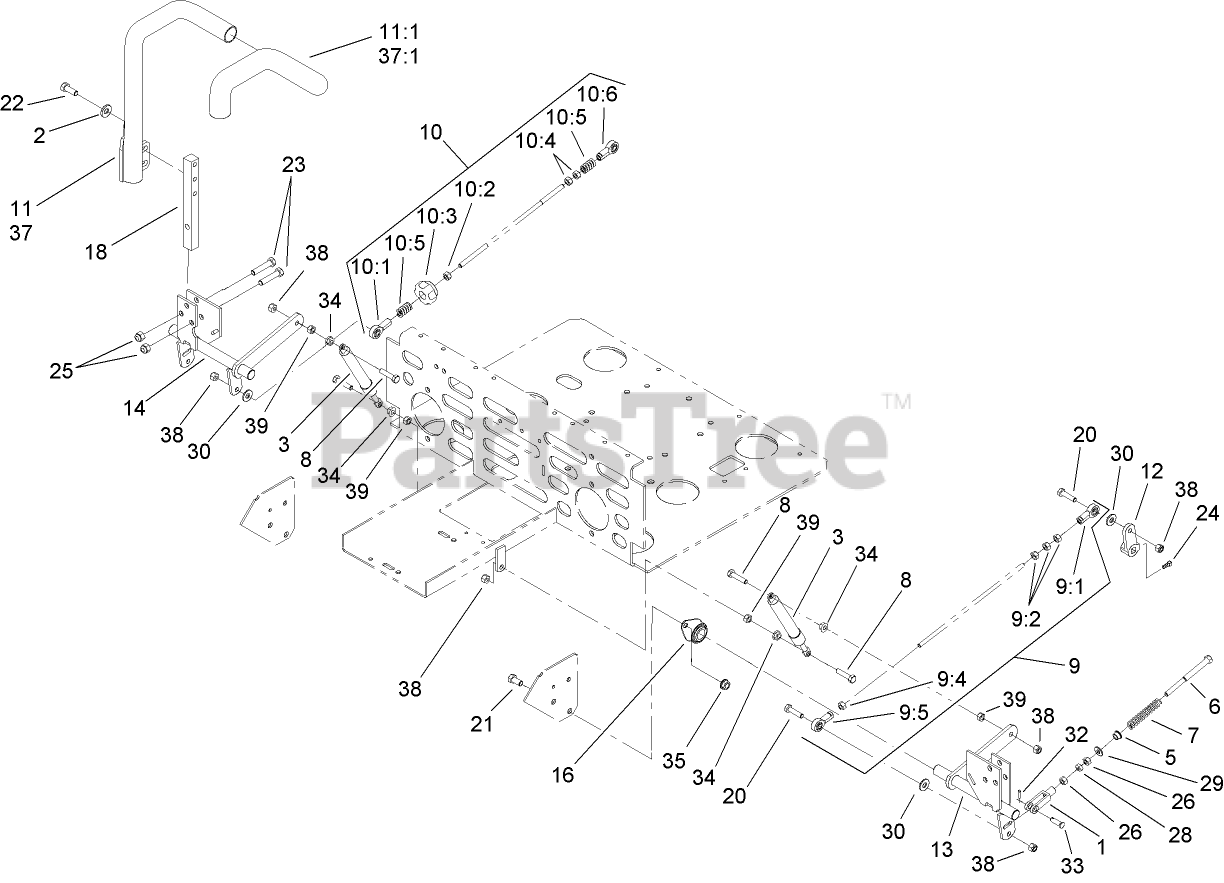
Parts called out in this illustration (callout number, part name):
1	YOKE-ADJUSTABLE
2	WASHER-BELLEVILLE
3	DAMPER-CONTROL, MOTION
5	BUSHING-FLANGED
6	BOLT-RETURN, NEUTRAL
7	SPRING-RETURN, NEUTRAL
8	SCREW-HH
9	Tracking Rod ASM
9:1	BALLJOINT-RH
9:2	NUT-HEX
9:5	BALLJOINT-LH
10	Tracking Rod ASM
10:1	BALLJOINT-RH
10:2	NUT-HEX
10:3	KNOB-TRACKING
10:5	SPRING-COMPRESSION
10:6	BALLJOINT-LH
11	LH LEVER ASM
11:1	Grip-Control, Motion
12	ARM-CONTROL, PUMP
13	Control-Motion, LH
14	Control-Motion, RH
16	BEARING-FLANGE, SIDE
18	ARM-SHAFT, CONTROL
20	SCREW-HH
21	SCREW-HH
22	SCREW-HH
23	SCREW-HH
24	SCREW-SET
25	NUT-LOCK, NI
26	NUT-HEX
28	NUT-JAM
29	WASHER-FLAT
30	WASHER-FLAT
32	PIN-COTTER
33	PIN-CLEVIS
34	NUT-HF
35	NUT-HHF, WHIZ
37	RH LEVER ASM
37:1	Grip-Control, Motion
38	NUT-LOCK, NI
39	NUT-HEX
